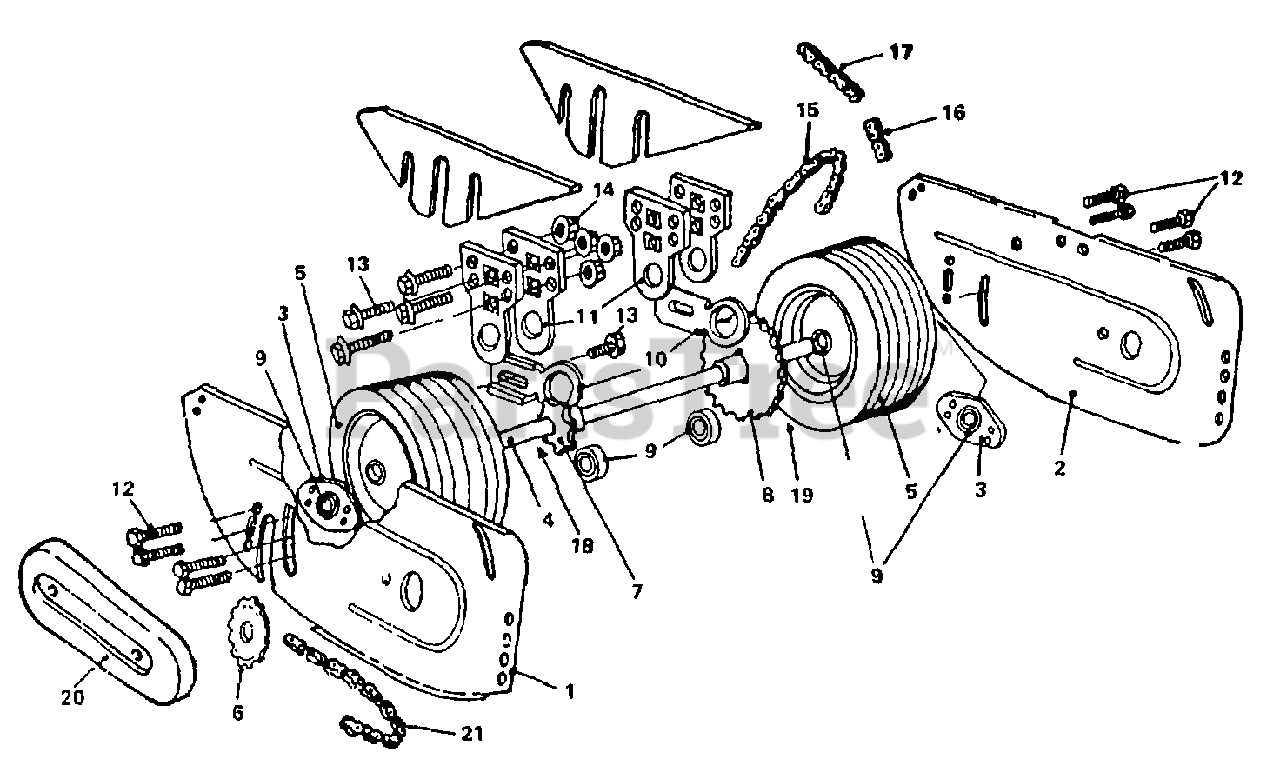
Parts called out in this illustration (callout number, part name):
1	SIDEPLATE (RIGHT)
2	SIDEPLATE (LEFT)
3	SIDEPLATE BEARING RETAINER
4	REAR AXLE (20")
4	REAR AXLE (25")
5	REAR WHEELS (20") W/BEARINGS - EA.
5	REAR WHEELS (25") W/BEARINGS - EA.
6	SPROCKET (17 TEETH)
7	SPROCKET (8 TEETH)
8	SPROCKET (30 TEETH)
9	SEALED BEARING (8 REQ.)
10	ROLLER BRACKET SUPPORTS
11	AXLE HANGERS
12	5/16-18x1/2 BOLT
13	5/16-24x7/8 BOLT
14	5/16-24 NUT
15	ROLLER DRIVE CHAIN - 46 PITCH
16	2-LINK #41 CHAIN W/MASTER LINK
17	4-LINK #41 CHAIN W/MASTER LINK
18	SPACER (20") - RIGHT
18	SPACER (25") - RIGHT
19	SPACER (20") - LEFT
19	SPACER (25") - LEFT
20	CHAIN GUARD
21	SIDEPLATE CHAIN
